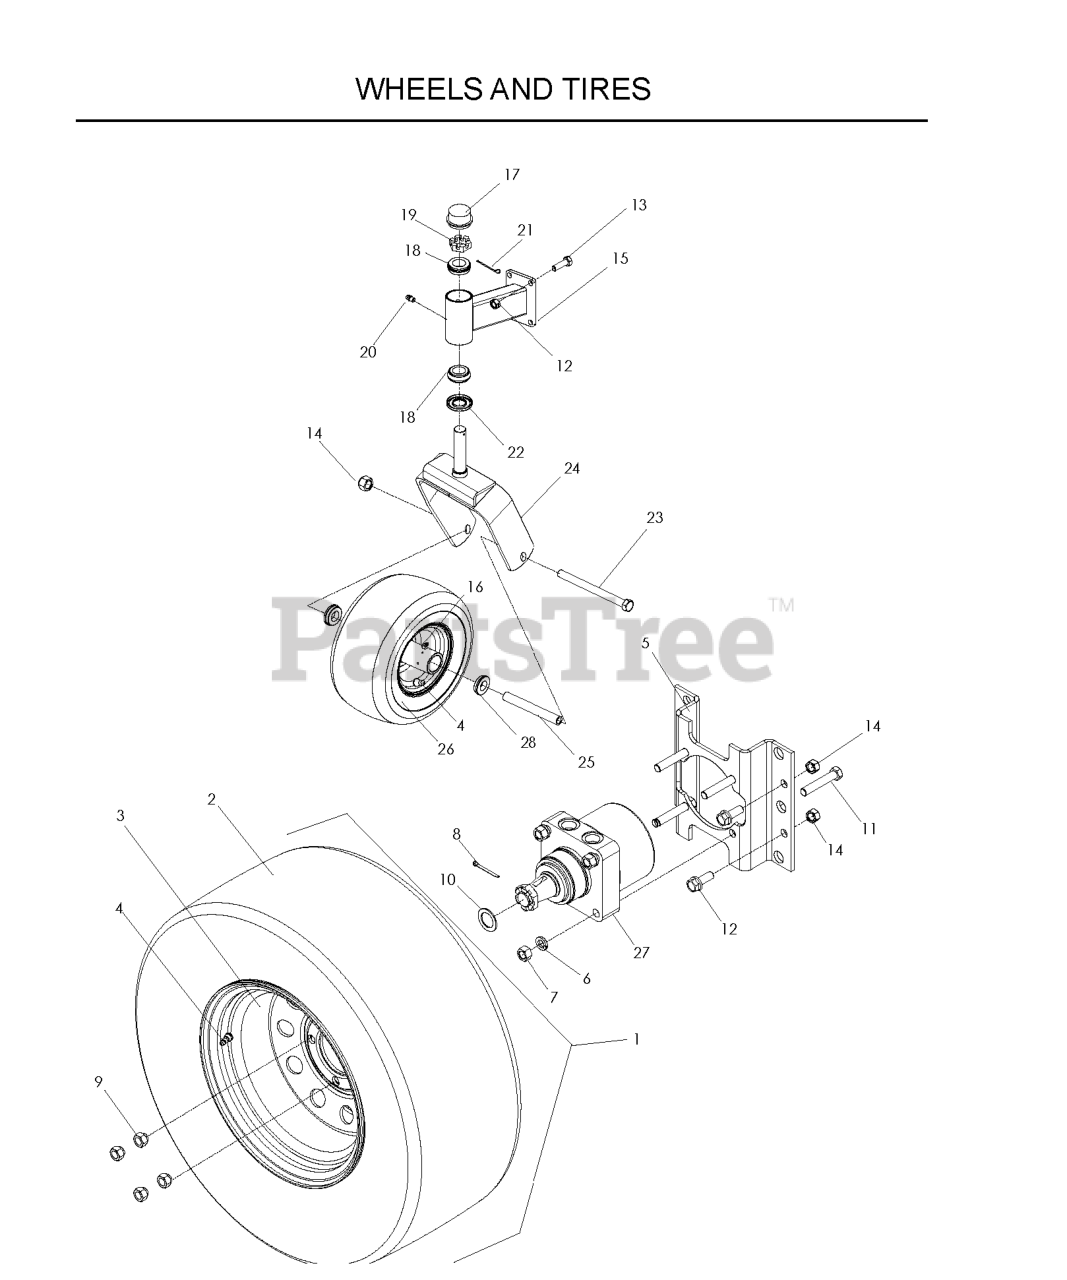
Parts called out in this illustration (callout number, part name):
1	WHEEL/TIRE.ASM.23X9.5-12.GREY
2	TIRE.TURF.MASTER.23X9.5-12
3	RIM, 12 X 7, 1" NEG OFFSET
4	VALVE STEM TR-412
5	MOTOR STANDOFF
6	WASHER 1/2" SPLIT LOCK
7	NUT HEX 1/2
8	PIN COTTER 4MM X 45MM
9	LUG NUT 1/2F
10	MACHINE BUSHING
11	HCS 1/2C X 2 3/4
12	NUT 7/16C CENTERLOCK
13	HCS 7/16-14 X 1 GR 5 ZD
14	NUT 1/2-13 HEX NYLOC ZD
15	CASTER ARM, ORG
16	ZERK 1/8 NPT
17	GREASE CAP
18	TAPERED ROLLER BRG
19	NUT 1"C HEX SLOTTED
20	ZERK
21	COTTER PIN 1/8 X 2
23	SCREW 1/2C X 7 1/2 HEX CAP
24	CASTER YOKE ORANGE
25	SPACER, CASTER
26	TIRE.ASSEM.13X5-6.SMOOTH.SILVE
27	TL15 WHEEL MOTOR
28	BEARING RETAINER
